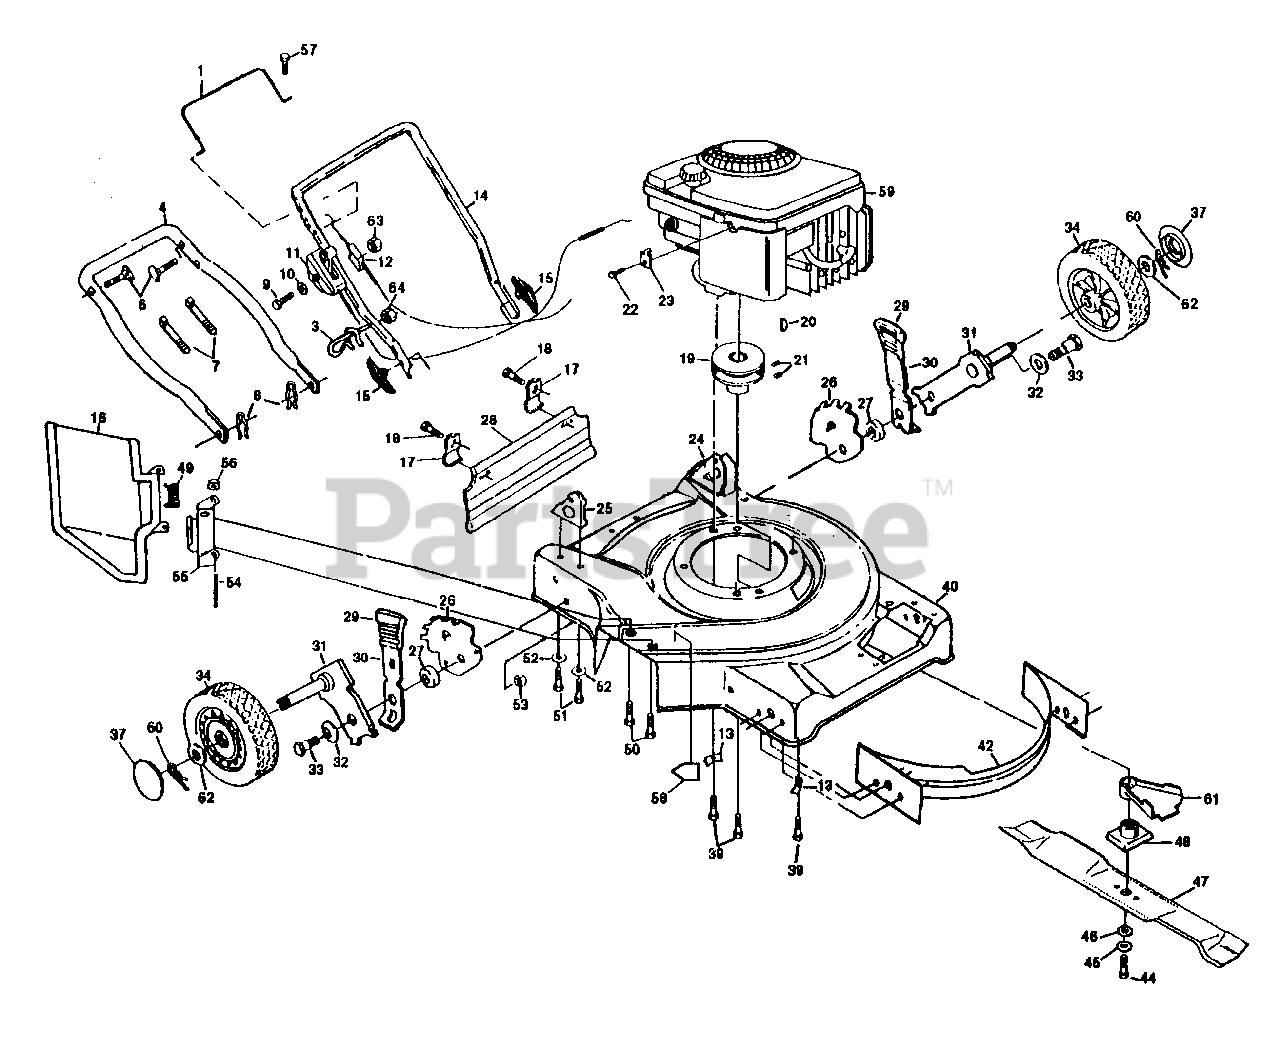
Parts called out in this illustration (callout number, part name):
1	Control Bar (AYP part number)
3	Rope Guide
4	Lower Handle (AYP part number)
6	Handle Bolt (AYP part number)
7	Wire Tie (AYP part number)
8	Hairpin Cotter (AYP part number)
9	Machine Screw 1/4-20 x 2-1/4 (AYP part number)
10	Washer 9/32 x 5/8 x 1/16 (AYP part number)
11	Deluxe Throttle Control
12	Engine Zone Control Cable
13	Engine Washer (AYP part number)
14	Upper Handle (AYP part number)
15	Handle Knob (AYP part number)
16	Discharge Guard
17	Bracket Skirt (AYP part number)
18	Screw Hex Washer Head (AYP part number)
19	Engine Pulley (AYP part number)
20	Hi Pro Key #HP-505 (AYP part number)
21	Set Screw 1/4-20 x 5/16 (AYP part number)
22	Thread Rolling Screw #10-32 x 5/8 (AYP part number)
23	Cable Clamp (Engine) (AYP part number)
24	Handle Bracket Assembly (Left) (AYP part number)
25	Handle Bracket Assembly (Right) (AYP part number)
26	Wheel Adjuster Bracket (AYP part number)
27	Spacer (AYP part number)
28	Rear Skirt (AYP part number)
29	Selector Knob
30	Selector Spring (AYP part number)
31	Axle Arm Assembly (AYP part number)
32	Belleville Washer 1/2 (AYP part number)
33	Shoulder Bolt 3/8-16 (AYP part number)
34	Wheel & Tire Assembly (Rear) (AYP part number)
37	Hubcap (AYP part number)
39	Hex Head Thread Rolling Screw 3/8-16 x 1-1/8 (AYP part number)
40	Lawn Mower Housing Kit (Inc. 58)
42	Front Baffle (AYP part number)
44	Hex Head Machine Screw 3/8-24 x 1-3/8
45	Helical Lockwasher 3/8 (AYP part number)
46	Hardened Washer (AYP part number)
47	22" Blade
48	Blade Adapter
49	Torsion Spring (AYP part number)
50	Hex Head Thread Rolling Screw w/Sems 1/4-20 (AYP part number)
51	Thread Cutting Screw 5/16-18 x 3/4 (AYP part number)
52	Washer 5/16 (AYP part number)
53	Locknut 3/8-16 (AYP part number)
54	Hinge Rod (AYP part number)
55	Housing Bracket (AYP part number)
56	Push-on Speed Nut (AYP part number)
57	Self-tapping Screw #10-24 x 5/8 (AYP part number)
58	Danger Decal (Housing) (AYP part number)
60	Retainer Clip (AYP part number)
61	Shield Debris
62	Washer 17/32 x 1 x 21 Ga. (AYP part number)
63	Keps Locknut (AYP part number)
